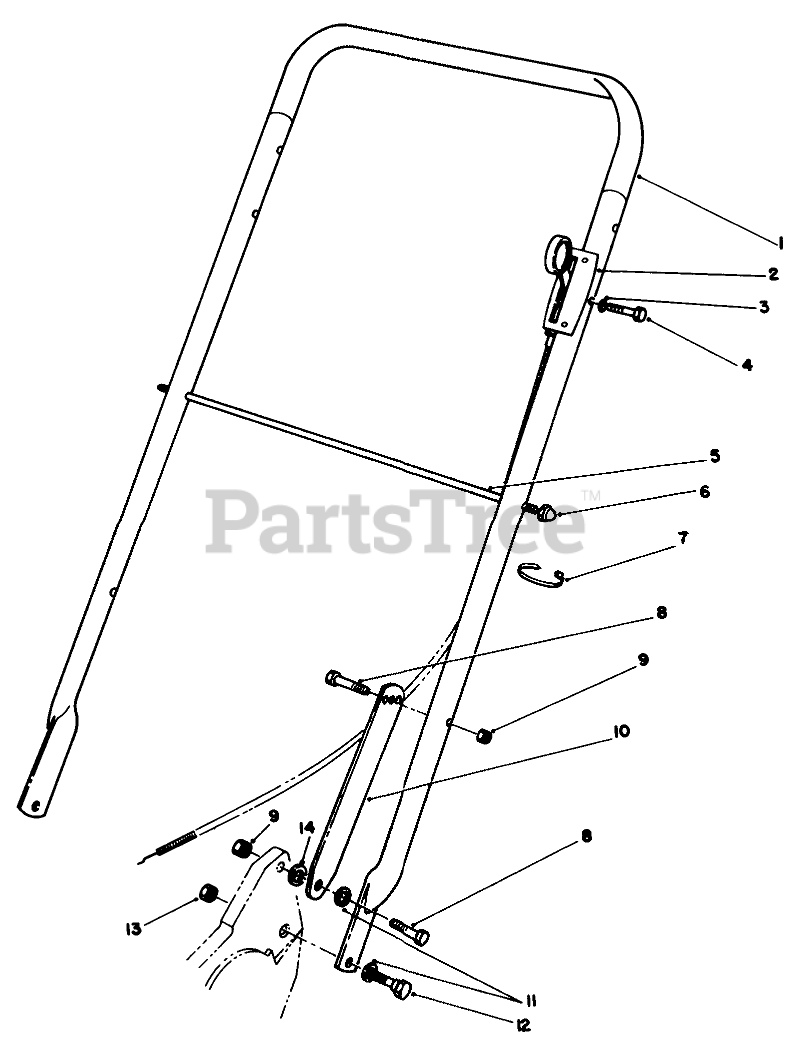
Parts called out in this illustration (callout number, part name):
1	Handle
2	Throttle Control Bend Type #2 Sheath Lg. 52.0 inch Wire Lg. 2.8 inch
3	WASHER
4	SCREW-HH
5	ROD-SUPPORT, BAG
6	NUT-CAP
7	TIE-CABLE
8	SCREW-HH
9	NUT-LOCK, NI
10	HANDLE LATCH
11	WASHER-BELLEVILLE
12	SCREW-HH
13	NUT-LOCK, NI
14	SPACER-PIN, MOUNTING
